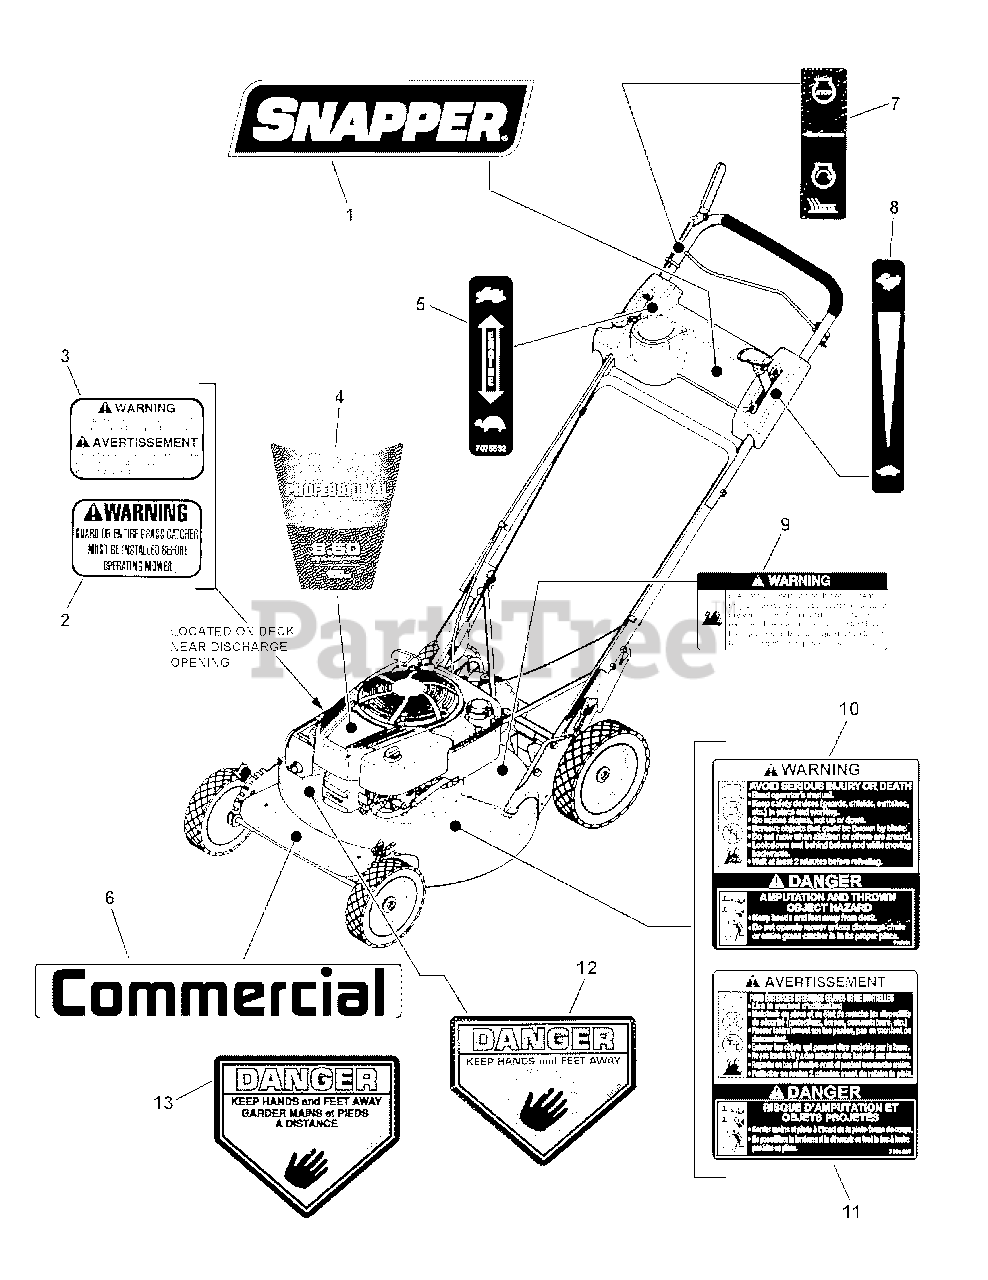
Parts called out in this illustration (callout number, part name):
1	DECAL, Logo, Snapper, 7.88"
2	DECAL, Chute Deflector
3	DECAL, Chute/Deflector FC
4	DECAL, 8.50T/190cc Professional Series
5	DECAL, Throttle Control, B&S
6	DECAL, Snapper, Steel Deck
7	DECAL, OPC Bail International Symbol
8	DECAL, Speed Shift
9	DECAL, Spark Arrestor
10	DECAL, Warning/Danger, Walk-Behind-Mower
11	DECAL, Warning/Danger, French/English
12	DECAL, Danger, Cut Finger
13	DECAL, CPSC, French/English
